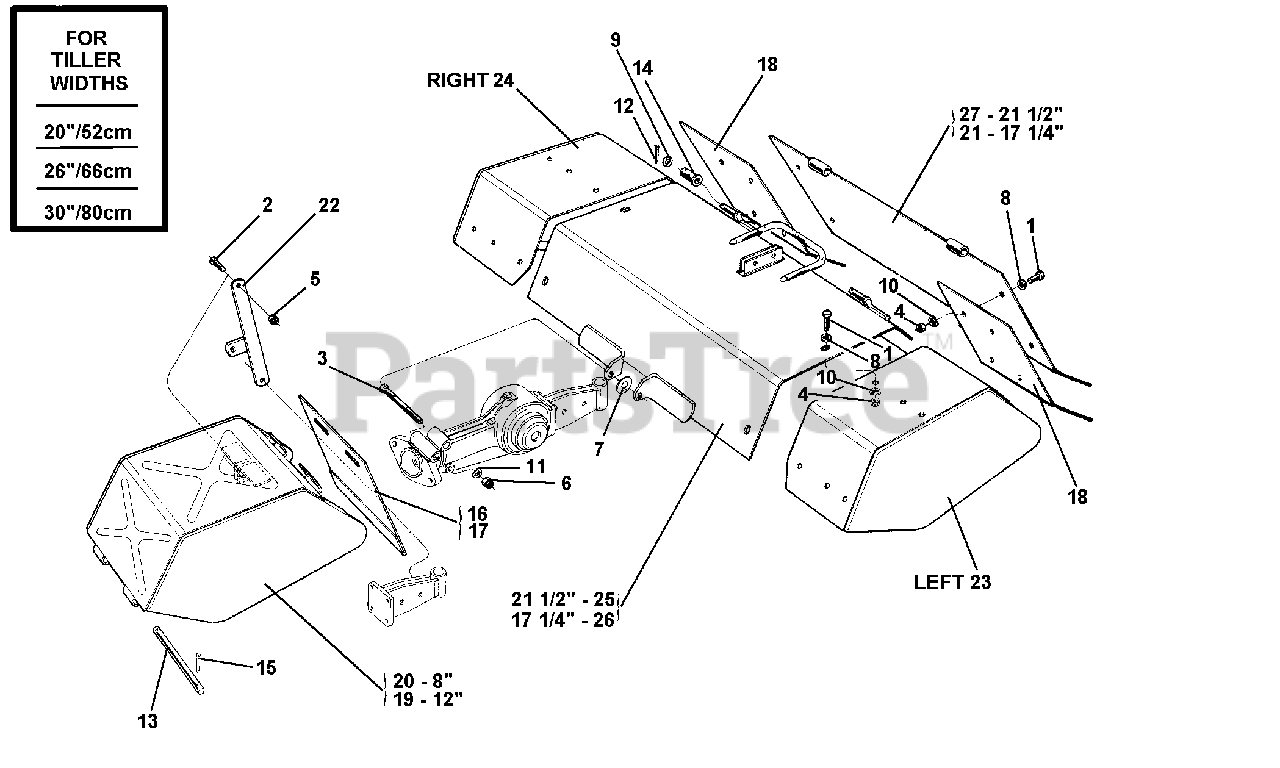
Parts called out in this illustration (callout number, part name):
1	SCREW M8 X 16
2	SCREW M8 X 25
5	NUT, SELF LOCKING M8
6	NUT, SELF LOCKING M12
7	FLAT WASHER
8	WASHER, FLAT 8.4
9	WASHER P10.5 X 18
10	WASHER, LOCK 8.4
11	WASHER, LOCK 13
12	COTTER PIN Z 3 X 15 UNI 1336 AC.
13	PIN, COTTER 4 X 25
15	PIN, HOOD
16	FLAP, HOOD L 300
17	FLAP, HOOD L 200
18	SIDE FLAP
19	ROTARY HOE COVER
20	ROTARY HOE COVER
21	CENTRAL FLAP
22	COVER ROD
23	LEFT SIDE
24	RIGHT SIDE
25	80 CM COVER CENTRAL CASING
26	COVER CENTRAL CASING
27	HOE CENTRAL FLAP
